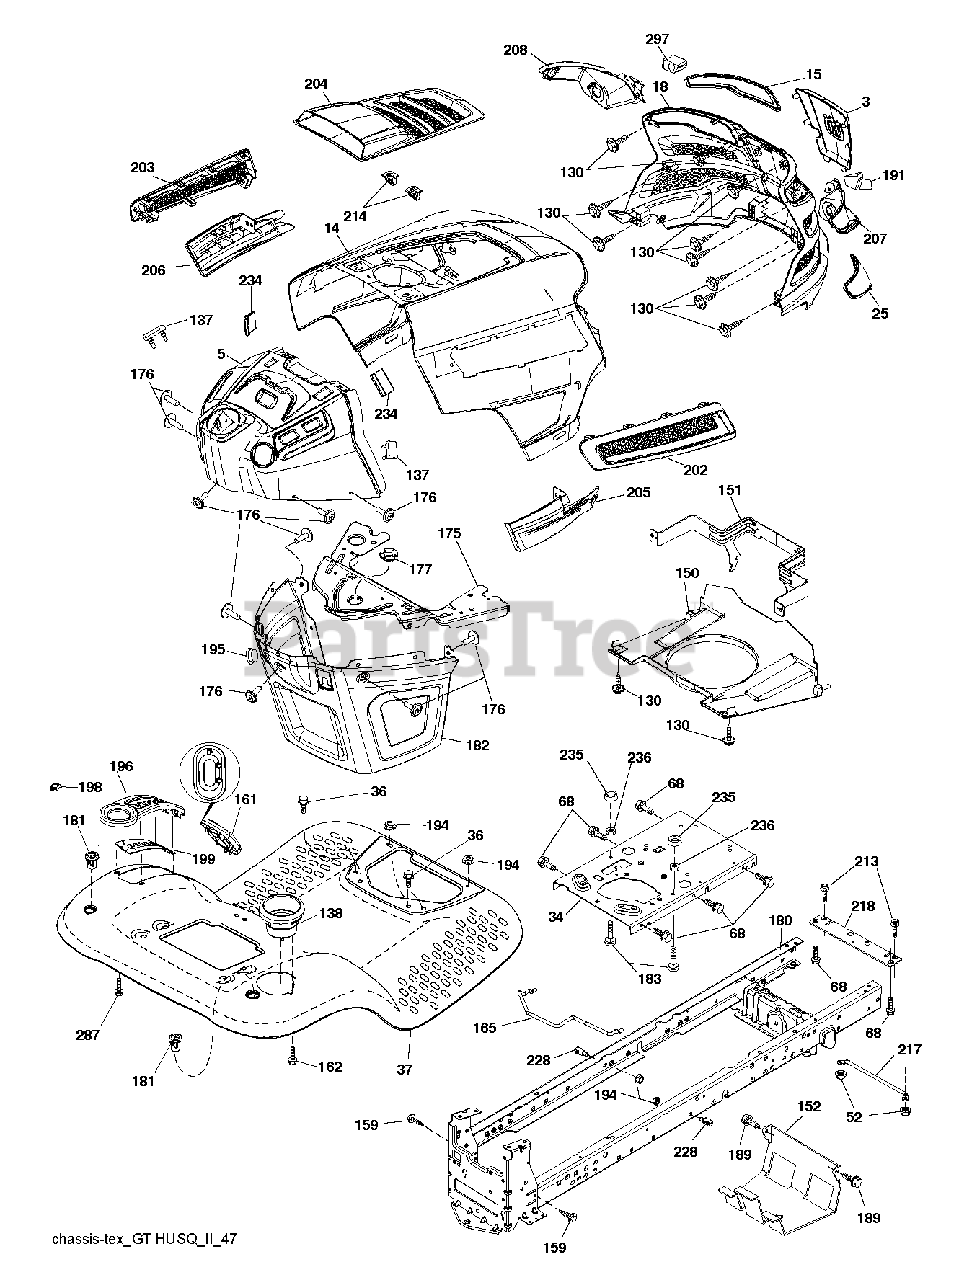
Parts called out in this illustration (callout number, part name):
3	APPLIQUE.SUBASM.GT.HUSQ.II
5	RP.DASH.UPP.GT2.SM.MC.CHOKE
14	HOOD.ASM.HUSQVARNA.GT.TEX.422
15	LENS.HEADLIGHT.LH.GTII.2011
18	GRILLE.SUBASM.GT.HUSQ.II
25	LENS.HEADLIGHT.RH.GTII.2011
34	PLATE.ENGINE.WELDED.CHASSIS
36	SCREW 5/16"
37	FENDER.TLT.W/CPH.W/FW.ORANGE
52	LOCKNUT
68	SCREW LT
130	SCREW.#10 X 0.750.BOS
137	BUMPER DASH
138	HOLDER.CUP.LT.GREY
150	AIR DUCT.GTV2(1.66"RING HEIGHT
151	BRACKET.PIVOT.HOOD.GT.HUSQ.II
152	SHIELD.BROWNING.W/TEX
159	SCREW, 3/8-16X3/4
161	WINDOW.FUEL.LT.HUSQ.TEX.418
162	SCREW.HI-LO.CONSOLE
165	SUPPORT.TANK.REAR.W/TEX
175	PLATE.CROSSMEMBER.HUSQ
176	SCREW.#10-24X5/8.RN.QU
177	BUSHING, STEERING
180	CHASSIS
181	BUSHING.MNT.FEND.CRGO.TEX.49
182	DASH.LOWER.COMMON.12V.ADAPTOR
183	BOLT.5/16-18X1-1/4 FULL THD
189	SCREW
191	INSERT.REFLECTIVE.RH.HUSQ.GTII
194	NUT LOCK HEX FLANGE 5/16-18
195	PLUG.HOLE.DASH.LOWER.12V.BLK
196	RP CONSOLE.ASM.DECKLFT.GR/RBT.
198	INDICATOR.DECK.LIFT.RED
199	PLATE.DECK.LIFT.HUSQ.LT
202	VENT.SIDE.RH.GT.HUSQ.II.
203	VENT.SIDE.LH.GT.HUSQ.II.498
204	VENT.TOP.HUSQ.GT2
205	SIDE.TRIM.RH.GT.HUSQ.II
206	SIDE.TRIM.LH.GT.HUSQ.II.GRAY
207	BEZEL LIGHT.RH.GT.II.MYLAR
208	BEZEL LIGHT.LH.GT.II.MYLAR
213	BOLT
214	CLIP.RETAINER.TINNER.
217	ROD.PIVOT.HOOD
218	X-PIECE.HOOD.STOP.NON/
228	STUD.FASTNER.W/ANTI-ROTATE
234	BUMPER.HOOD.TEX.HUSQVARNA
235	SPACER FENDER
236	NUT.CENTERLOCK.5/16-
287	SCREW 1/4X20
297	INSERT.REFLECTIVE.LH.HUSQ.GTII
